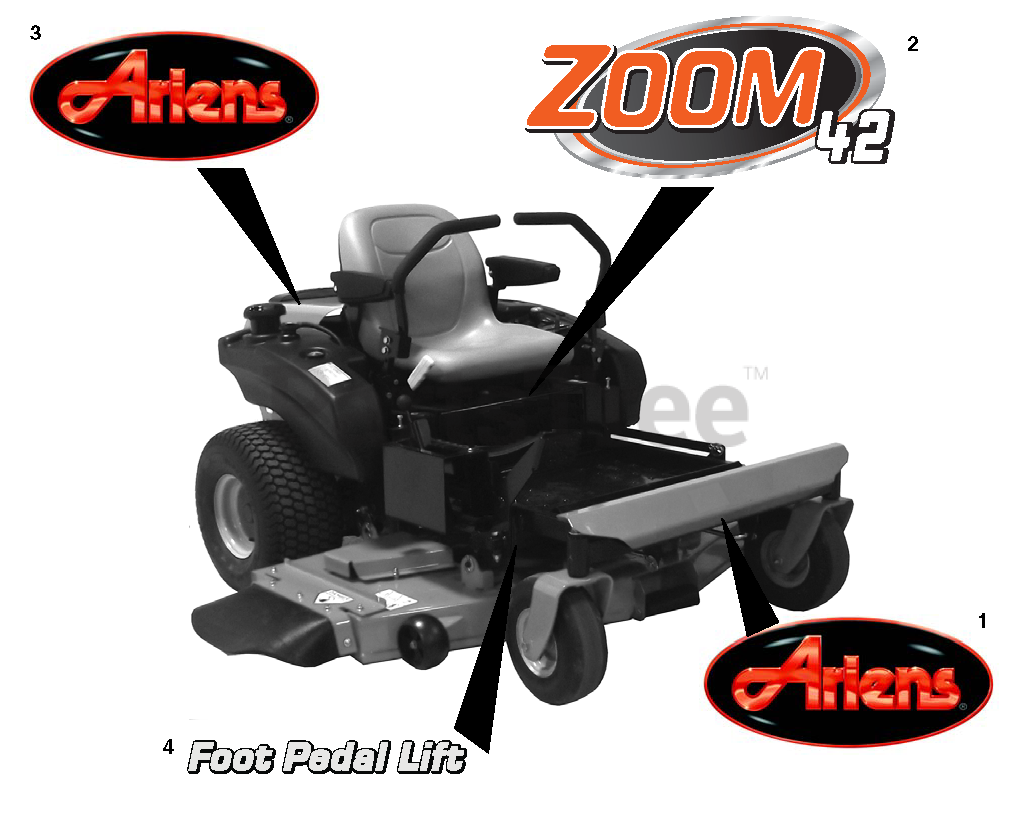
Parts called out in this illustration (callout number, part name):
1	DECAL, ARIENS JEWEL (LARGE)
2	DECAL, ZOOM42
3	DECAL, ARIENS JEWEL
4	DECAL, FOOT PEDAL LIFT
